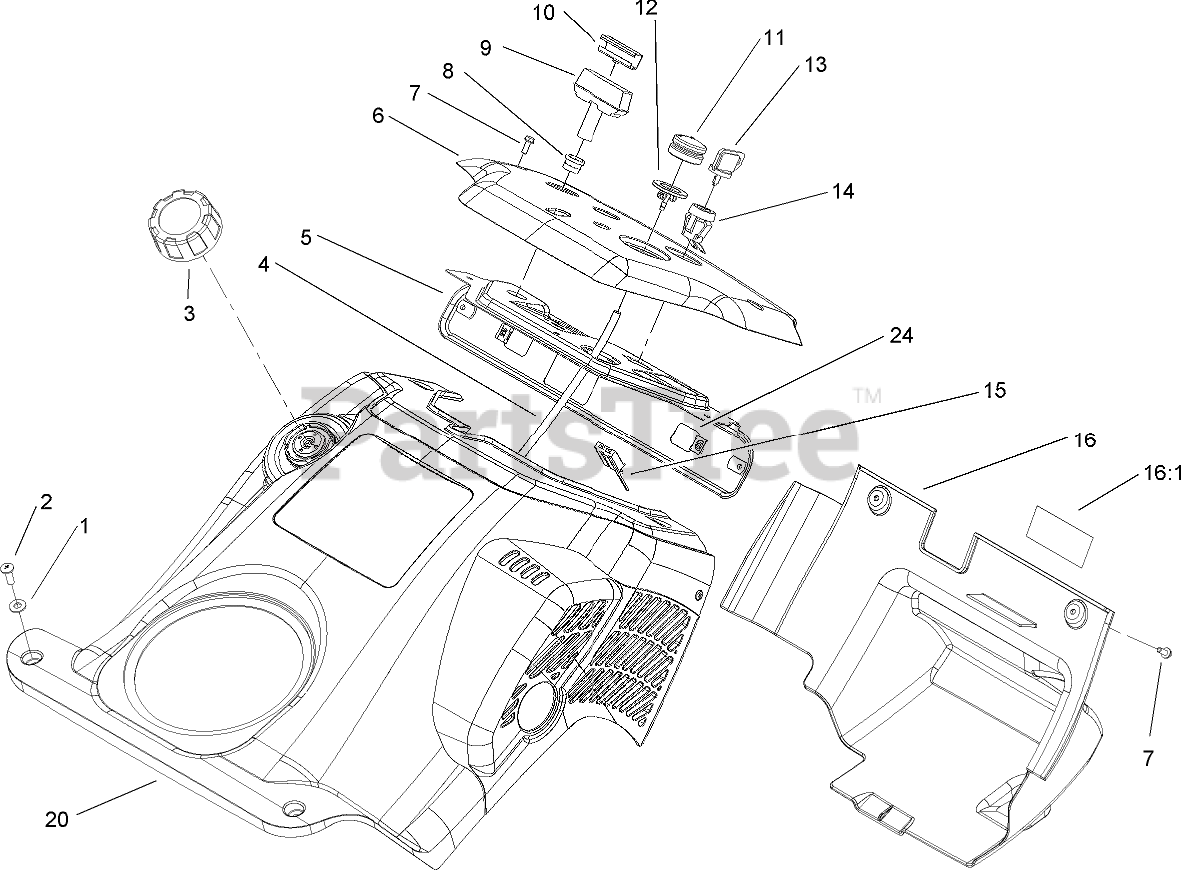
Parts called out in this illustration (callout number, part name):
1	WASHER-FLAT
2	SCREW-PPH
3	GAS CAP ASM
4	HOSE-PRIMER
5	PANEL-SUPPORT, CONTROL
6	PANEL-CONTROL
7	SCREW-HWH
8	GUIDE-ROPE, STARTER
9	HANDLE-START
10	CLIP-STARTER
11	BULB-PRIMER
12	BODY-PRIMER
13	KEY-IGNITION
14	SWITCH
15	CONNECTOR-BODY
16	SHROUD-LOWER W/DECAL
16:1	DECAL
20	UPPER SHROUD ASM
24	NUT-SPEED
